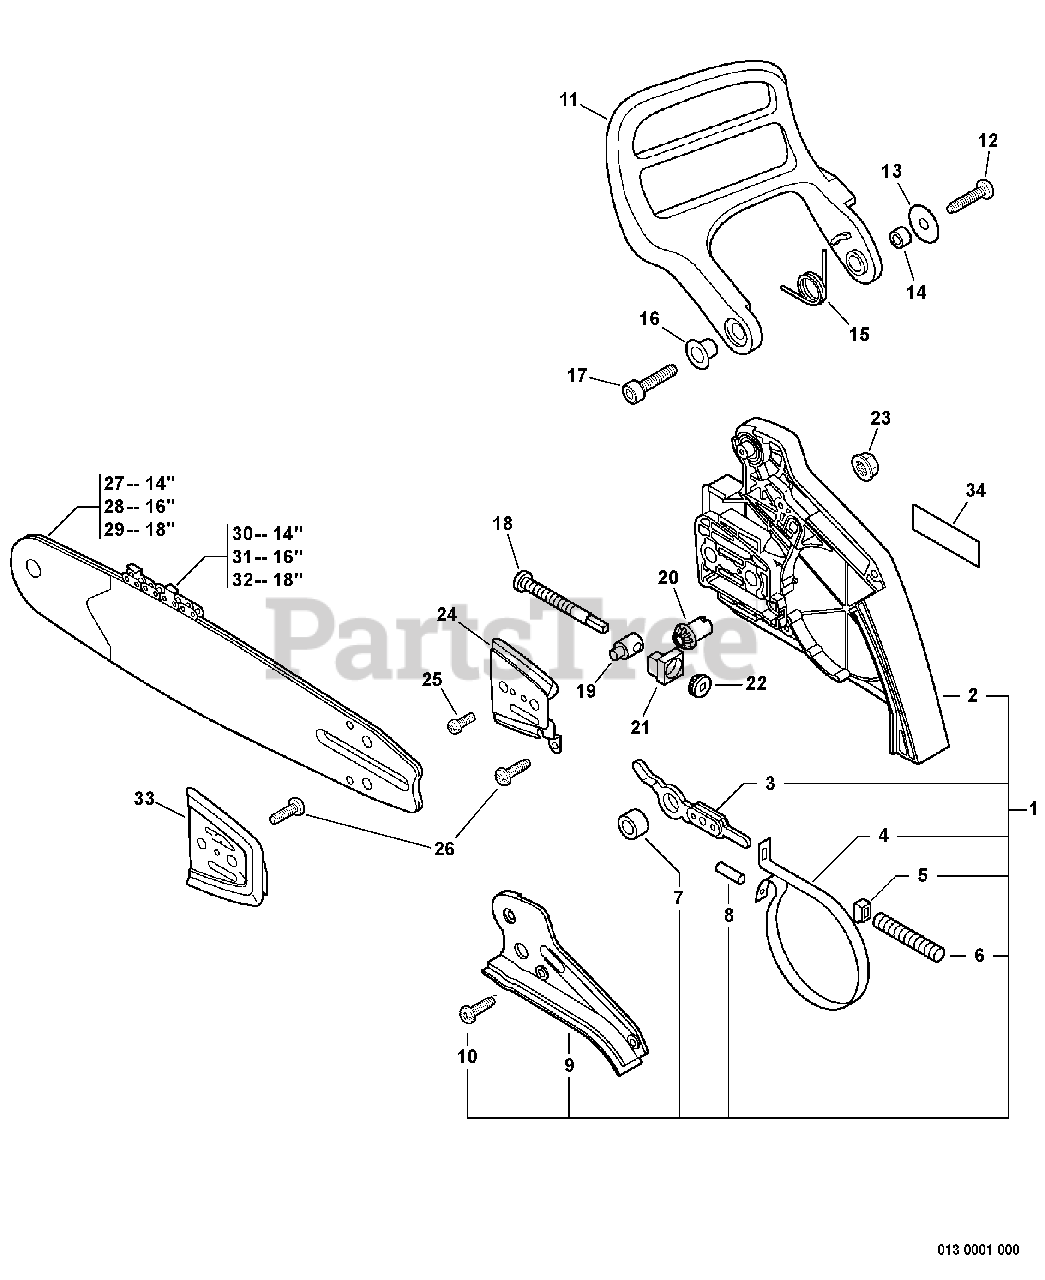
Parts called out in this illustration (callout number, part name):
1	CHAIN BRAKE ASSY
2	GUARD, SPROCKET
3	CONNECTOR, BRAKE
4	BAND, BRAKE
7	SPACER - 8
8	PIN - SPRING
9	COVER, BRAKE
10	SCREW - 4X12 -- TAPPING
11	LEVER, BRAKE
12	SCREW - 4X16
14	SPACER - 8
16	COLLAR - 10
17	SCREW - 5X16
18	SCREW, TENSIONER
19	TENSIONER, CHAIN
20	GEAR - PINION
21	COLLAR - 8
22	GEAR - BEVEL
23	NUT - FLANGE
24	PLATE, GUIDE - OUTER
25	SCREW - 3X6
26	SCREW - 4X8
27	GUIDE BAR - 14" (35cm)
28	GUIDE BAR - 16" (40cm)
29	GUIDE BAR - 18" (45cm)
30	SAW CHAIN - 14" (35cm)
31	SAW CHAIN - 16" (40cm)
32	SAW CHAIN - 18" (45cm)
33	PLATE, GUIDE - INNER
34	LABEL - ECHO
